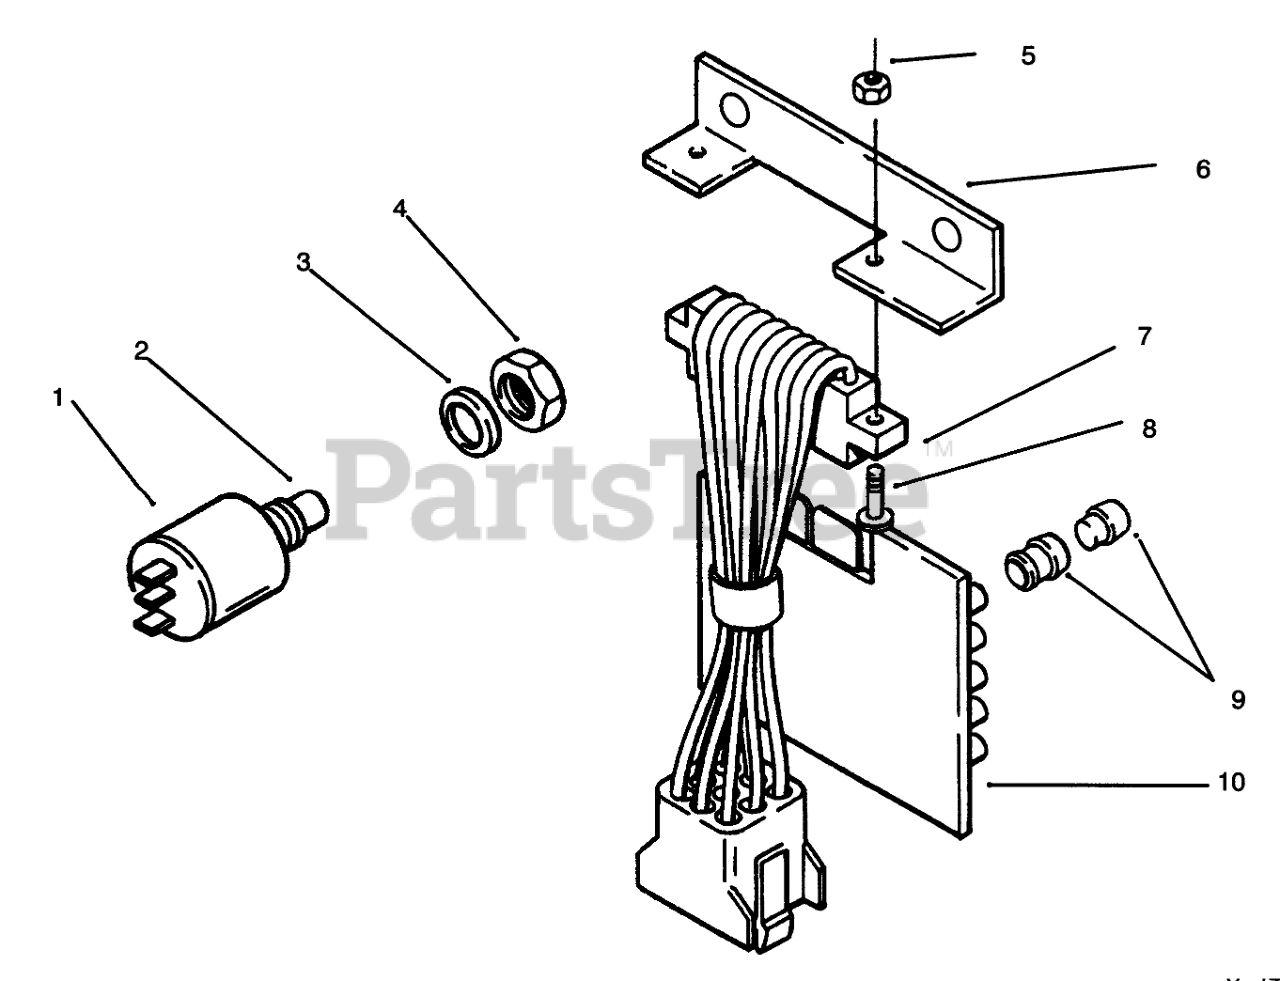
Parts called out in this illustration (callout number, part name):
1	SWITCH-PUSH BUTTON
2	Switch-Button (Incl. Ref. #2-4)
3	Washer
4	NUT F/W 116796
5	NUT HEX 4-40 ELAST
6	BRACKET
7	P.C.-BOARD HARNESS
8	Screw
9	ASSY LENS & BUSHING
10	Board-Pc
